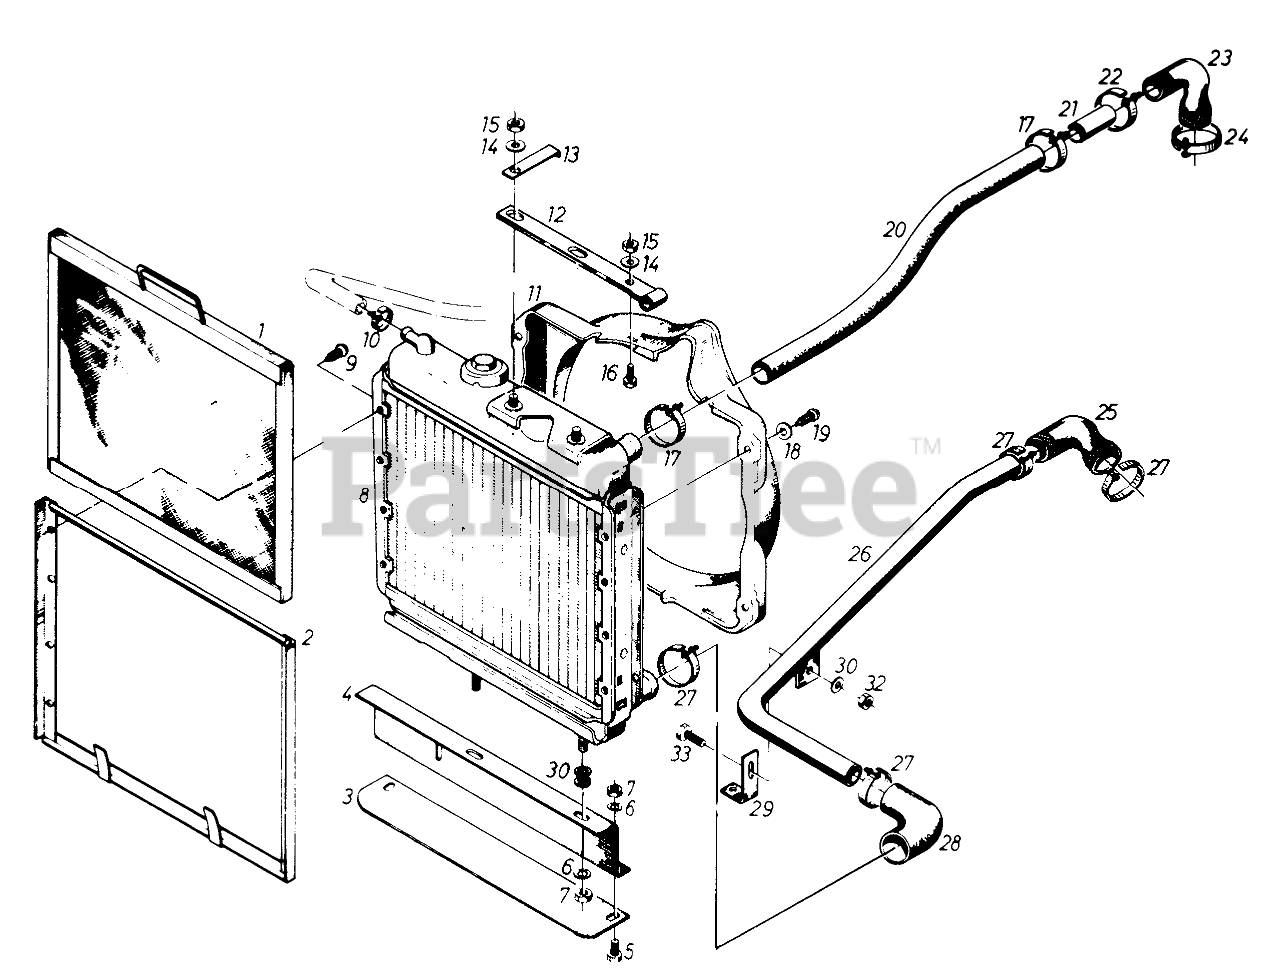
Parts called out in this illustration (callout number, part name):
1	Frame Cpl.
2	Frame Support Assy
3	Protection Plate
4	Radiator Support
6	Lockwasher
8	Radiator with Air Guide
9	Screw
10	Clamp
11	AIR GUIDE
12	Bracket
13	Support
14	Washer
17	Clamp
18	Washer
19	Screw
22	Clamp
23	Hose-lnlet
24	Clamp
25	Hose Outlet Elbow
26	Tube Assy
27	Clamp
28	Rubber Elbow
29	Bracket (S Hose)
30	Washer
